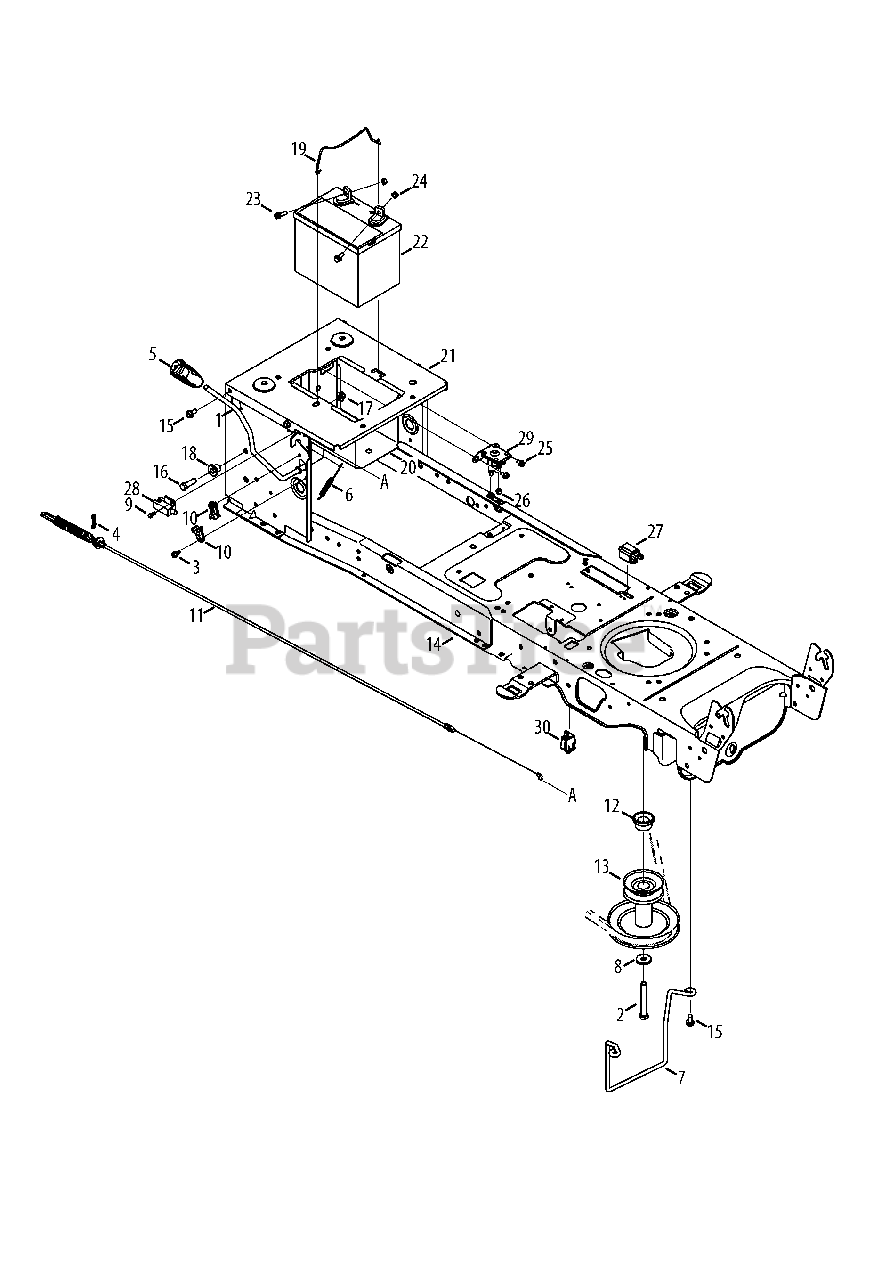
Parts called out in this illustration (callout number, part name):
1	Handle Ass’y, PTO
2	Hex Screw, 7/16-20, 3.50, Gr5, Lock
3	Screw, Self-tapping, 1/4-20, 0.50
4	Pin, Cotter, Bow-Tie 72
5	Grip, Handle, 3/8
6	Spring, Ext, .38 Dia x 5.6
7	Belt Keeper Rod
8	Washer, Flat, .450 x 1.250 x .164
9	Screw, Shoulder, #10-32, .500
10	Bearing, PTO
11	Cable, Engag, Deck
12	Spacer, 1.010 x 1.400 x .825
13	Pulley, Engine, 3.56 x 6.12 Dia.
14	Frame Ass’y, Lower
15	Screw, Self-tapping, 5/16-18, .750,
16	Hex Screw, 3/8-16, 1.25, Gr5, Std
17	Nut, Flange Lock, 3/8-16, Grf,
18	Spacer, Shoulder, .38 x 1.0 x .70
19	Rod, Battery
20	Tray, Battery
21	Bracket, Frame, Seat
22	Battery
23	Hex Flange Screw, 1/4-20, .75, Gr5
24	Nut, Sems, 1/4-20
25	Screw, Self-tapping, 1/4-20, 0.375,
26	Nut, Flange Lock, 1/4-20, Grf,
27	Switch, 3-Pole
28	Switch, Interlock
29	Solenoid, 12V
30	Switch, Plunger, Snap Mount
